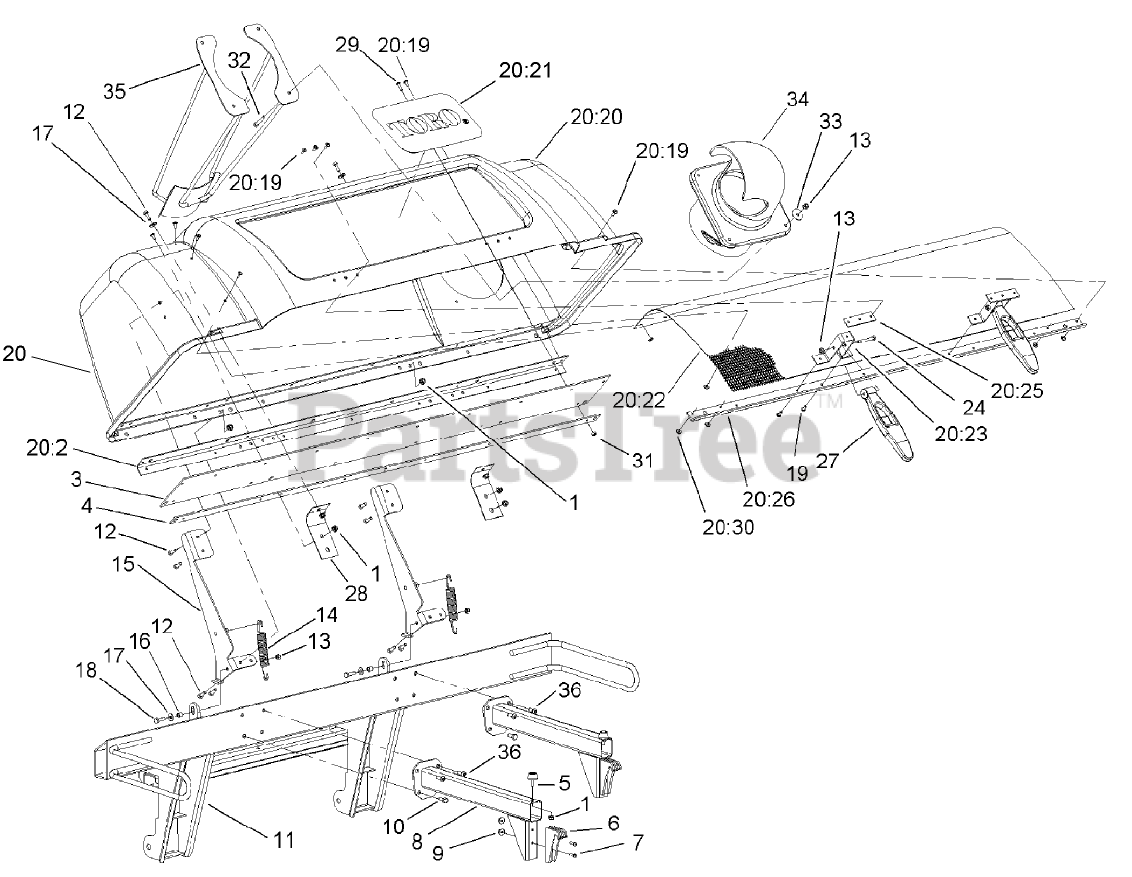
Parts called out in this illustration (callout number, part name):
1	NUT-HF
3	Seal-Hinge
4	Plate-Backing
5	BUMPER
7	SCREW-PPH
8	SUPPORT-BAG
9	NUT-HF
10	SCREW-HH
11	UPRIGHT BAGGER ASM
12	SCREW-HH
13	NUT-LOCK, NI
14	Spring-Extension
15	HINGE ASM
16	SPACER
17	WASHER-FLAT
18	SCREW-HH
19	RIVET-BLIND
20	Hood ASM
20:2	Stiffener-Bagger, Top
20:19	RIVET-BLIND
20:20	Hood-Bagger, Triple
20:21	DECAL
20:22	Screen-Bagger
20:23	Bracket-Mount
20:25	Plate-Latch, Reinforcement
20:26	Support-Screen
20:30	WASHER-FLAT
24	SCREW-HH
28	Reinforcement-Hood, Bagger
29	SCREW-HEAD, TRUSS
31	NUT-LOCK, SIDE
32	SCREW-HH
33	WASHER-FLAT
34	Tube-Bagger, Upper
35	FLEX HOSE SUPPORT ASM
36	SCREW-HSBH
